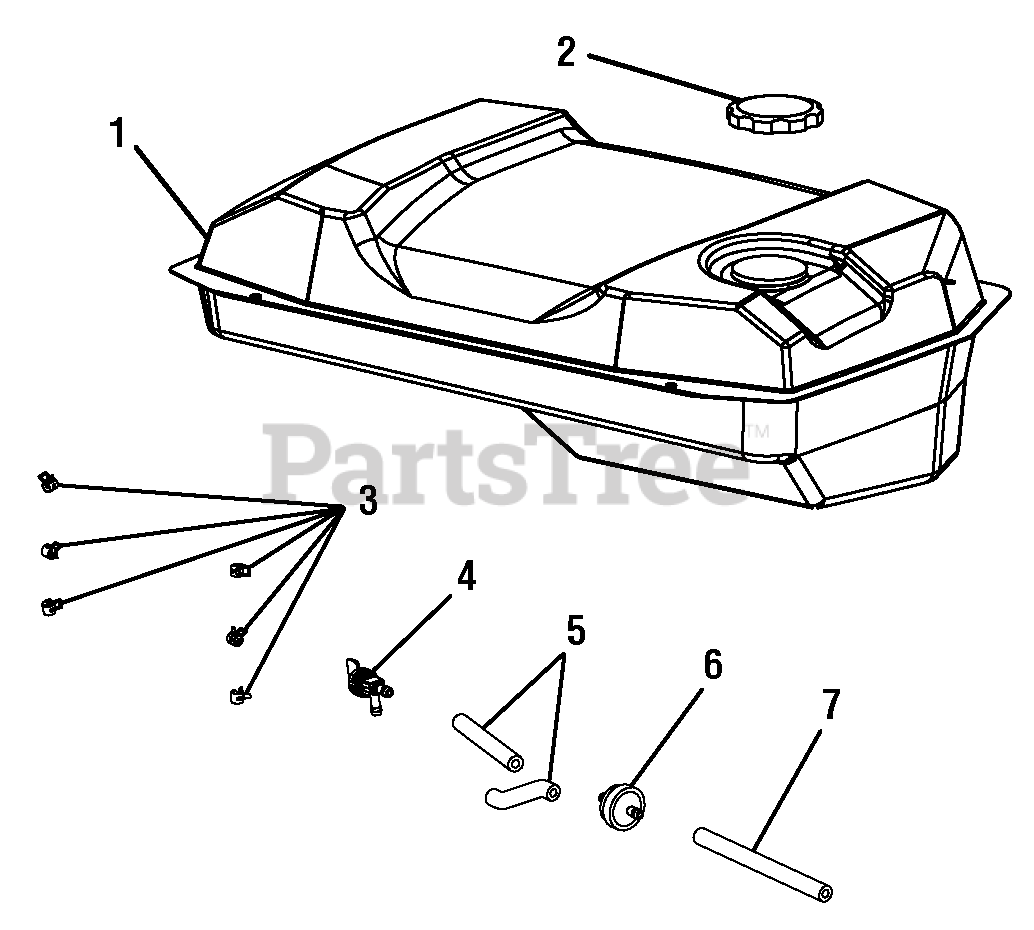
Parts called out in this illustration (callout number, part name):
1	Fuel Tank
2	Fuel Tank Cap
3	Fuel Line Clamp (1/2 in.)
4	Fuel Shut Off Valve
5	Fuel Line (6.4 mm x 105 mm)
6	Fuel Filter
7	Fuel Line (6.4 mm x 208 mm)
